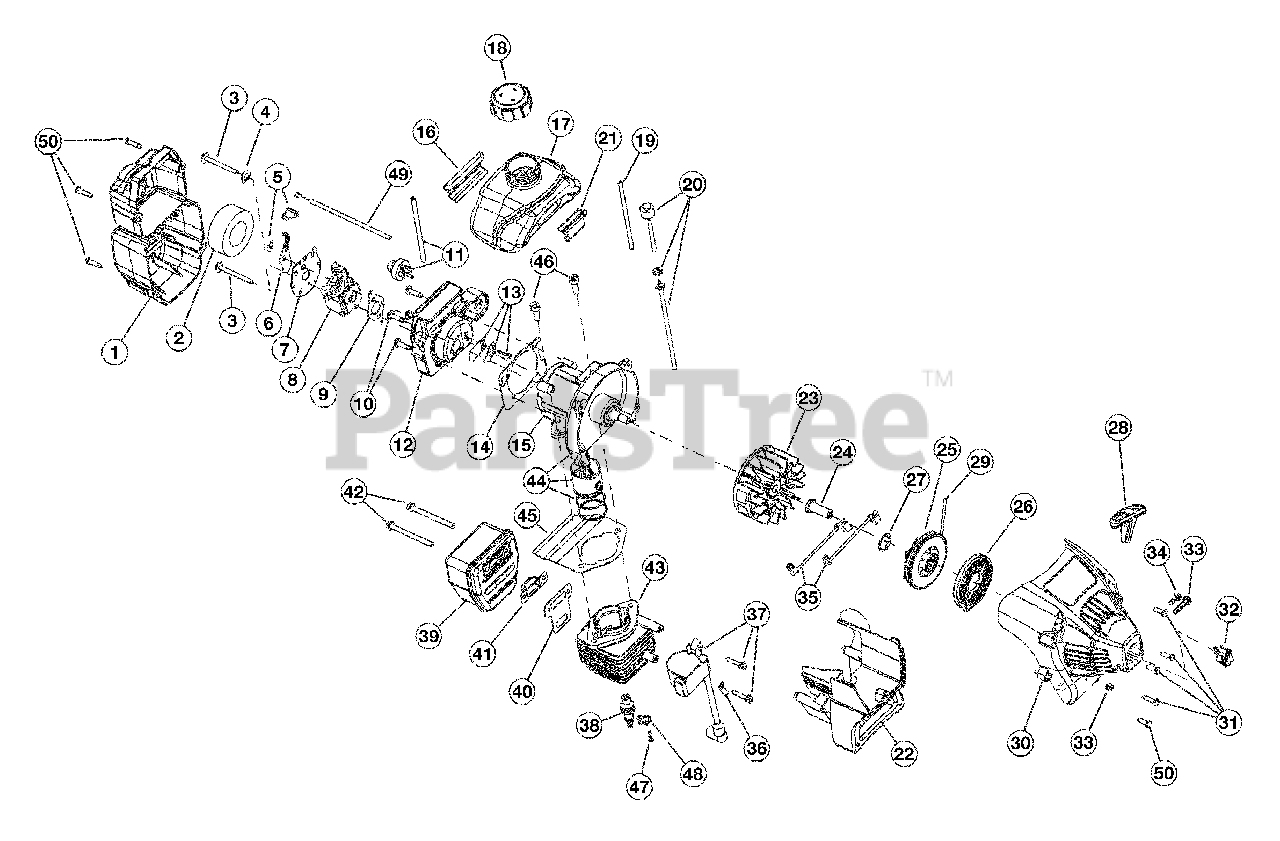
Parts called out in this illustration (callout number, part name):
1	Air Cleaner/Muffler Cover Assembly includes 2 & 47)
2	Air Cleaner Filter
3	Carburetor Mounting Screws
4	Wavey Washer
5	Choke Knob and Screw
6	Choke Lever Assembly (includes 5)
7	Choke Lever and Plate (includes 6)
8	Carburetor Assembly (includes 9 & 20)
9	Carburetor Gasket
10	Carb Mount Screw
11	Primer and Hose Assembly
12	Carb Mount Assembly (includes 10 & 13-14)
13	Reed Assembly
14	Carburetor Mount Gasket
15	Crank Case Service Assembly includes 10)
16	Rear Mounting Pad
17	Fuel Tank Assembly (includes 18-20)
18	Fuel Cap Assembly
19	Fuel Return Line
20	Fuel Line Assembly
21	Front Mounting Pad
22	Shroud Extension and Stand
23	Flywheel Assembly
25	Recoil Pulley
26	Recoil Spring
27	Pulley Retainer
28	Pull Handle
30	Starter Housing Assembly (includes 25-29, 31, 32 & 35)
31	Housing Screws
32	On/Off Switch
33	Clamping Screw & Nut
34	Anti-Rotation Screw
35	Wire Leads
36	Ground Tab
37	Module Assembly
38	Spark Plug
39	Muffler Assembly (includes 40-42)
40	Exhaust Gasket
41	Spark Arrestor Screen
42	Muffler Mounting Bolt
43	Cylinder Assembly (includes 45-48)
44	Piston and Rod Assembly w/Rings
45	Cylinder Gasket
46	Cylinder Bolt
47	Compression Relief Valve
48	Compression Relief Valve Spring
49	Compression Relief Valve Cable
50	Cover Screws
